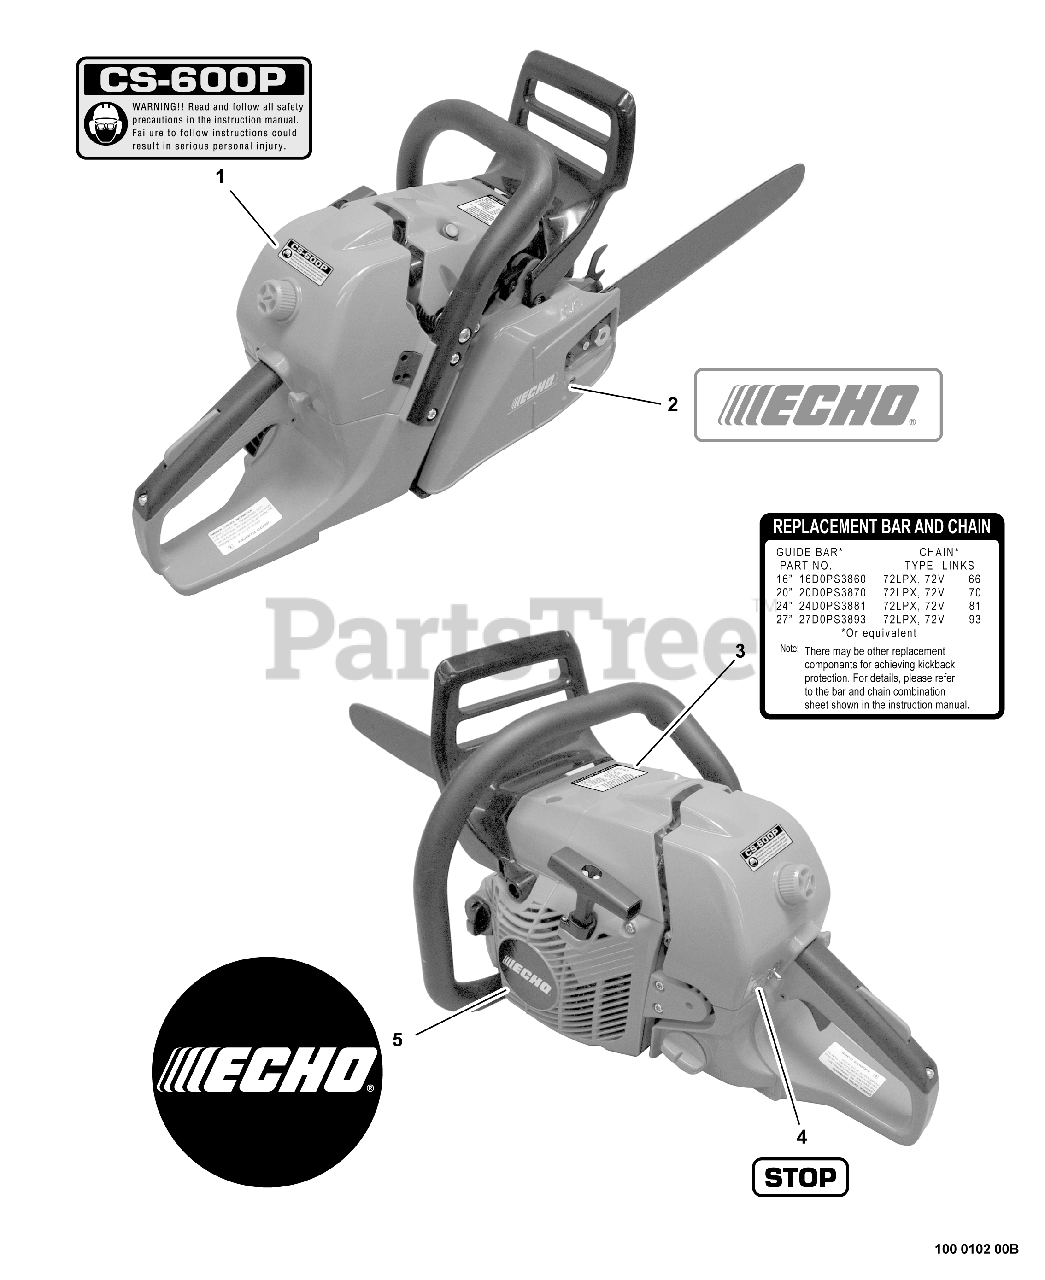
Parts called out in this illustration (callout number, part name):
1	LABEL - MODEL CS-600P
2	LABEL - ECHO
3	LABEL - BAR & CHAIN
4	LABEL - STOP
5	LABEL - ECHO
